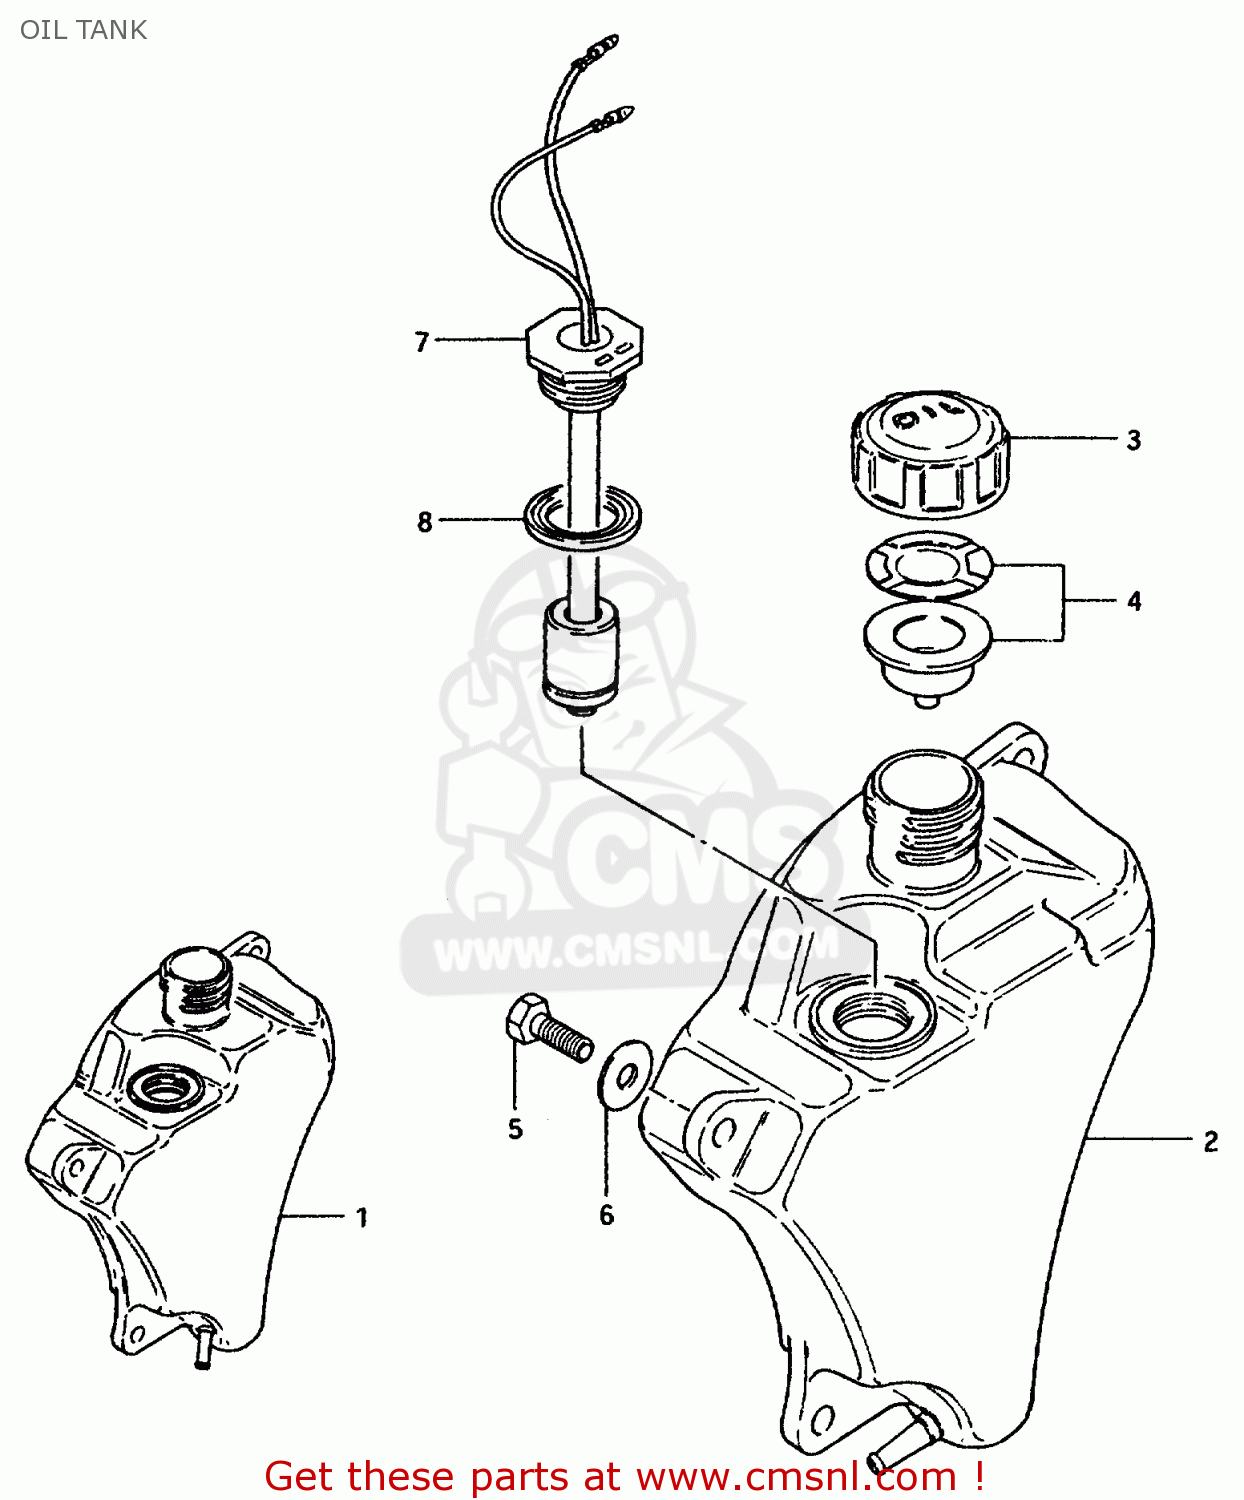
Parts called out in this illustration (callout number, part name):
1	TANK, OIL
2	TANK, OIL
3	CAP,OIL TANK
4	GASKET SET (NAS)
5	BOLT, UPPER
6	WASHER
7	SWITCH, OIL LEVEL
8	GASKET (NAS)
